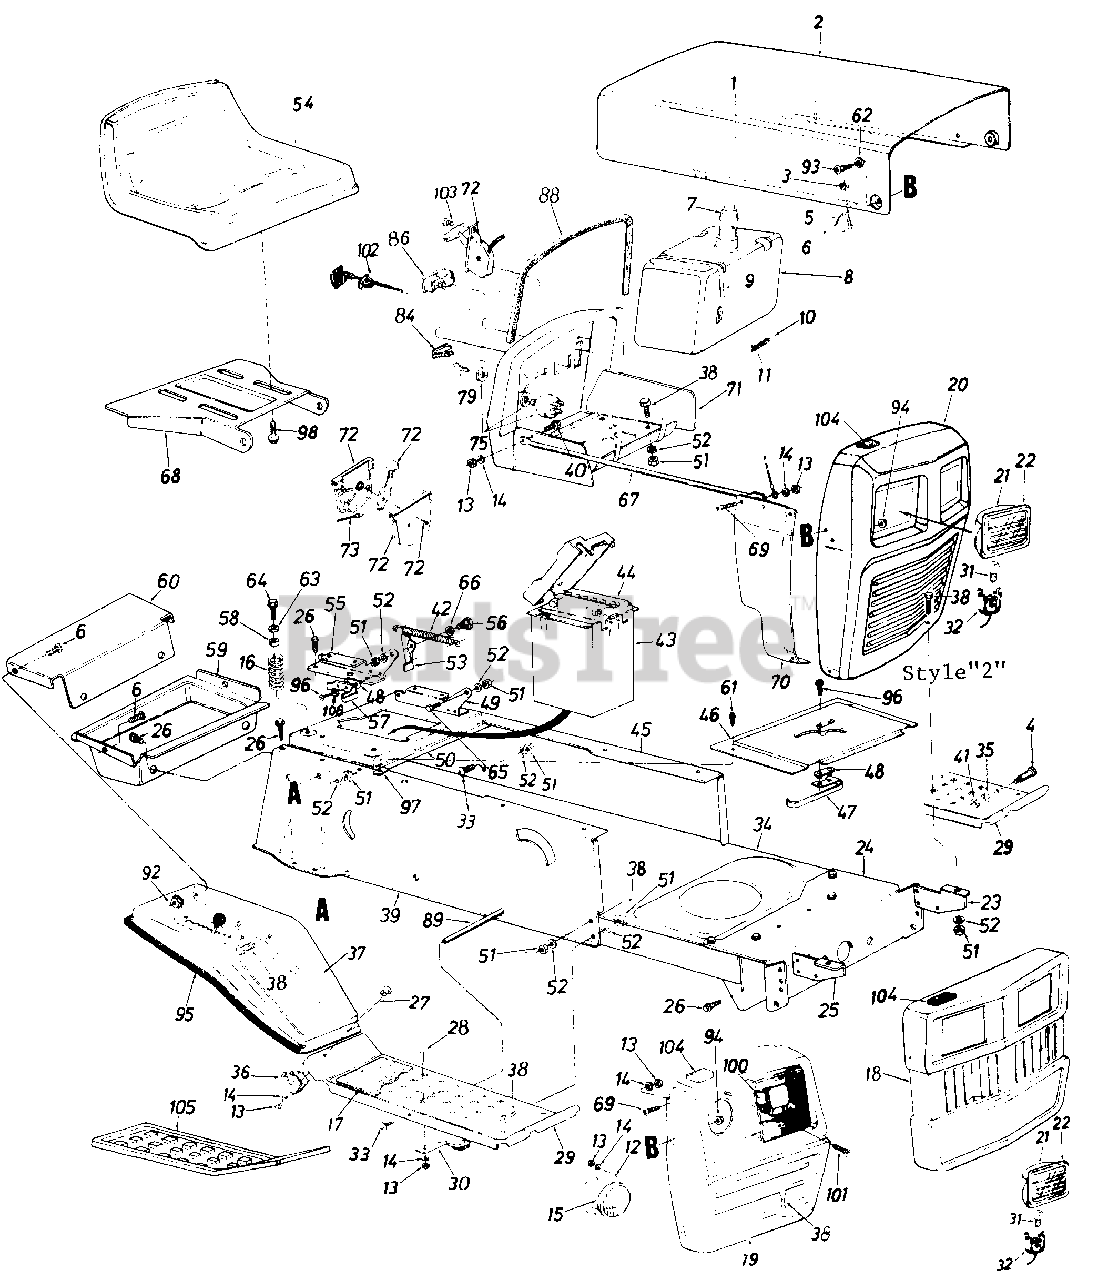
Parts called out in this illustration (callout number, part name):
1	Hood Spring
2	Hood
3	Hex Sems Nut #10-24 Thd.
4	Shld. Bolt .50" Dia. x .84"
5	Hood Stop 7" Lg.
6	Truss Hd. Scr. #10-24 x 1/2"
7	Fuel Cap Gauge
8	Fuel Tank
9	Tie Strap
10	Fuel Line
11	Hose Clamp
12	Headlight Retainer
13	Hex Nut 1/4-20 Thd.
14	L-Wash. 1/4" I.D.
15	Headlight*
16	Compression Spring
17	Foot Pad
18	Grille-Square Lights
22	Headlight Lens
23	Mounting Brkt.
24	Front Pivot Brkt.
25	Mounting Brkt.
26	Hex Wash. Hd. AB-Tap Scr. 5/16 x .75" Lg.
27	Carriage Bolt 1/4-20 x 2.0" Lg.*
28	Carriage Bolt 1/4-20 x .62"
29	Running Board
30	Blade Brake Ass'y.
31	Head Lamp
32	Twist Lock Lamp Socket
33	Truss Mach. Scr. 5/16-18 x .75" Lg.
34	Lower Frame
35	L-Wash. 3/8" I.D.
36	Fender Clamp
37	Fender
39	R.H. Side Frame
40	Hex Bolt 1/4-20 x .62" Lg.
41	Hex Nut 3/8-16 Thd.
42	Extension Spring 5.31" Lg.
43	Battery Box w/Cover
44	12-V Battery
45	L.H. Side Frame
46	Shift Cover
47	Reverse Safety Switch
48	Insulator Nut Plate
49	Seat Pivot Brkt. Support-L.H.
50	Hitch Plate
51	Hex Nut 5/16-18 Thd.
52	L-Wash. 5/16" I.D.
53	Seat Lift Brkt.
54	Seat 8-7/8" High
55	Seat Pivot Brkt. Support-R.H.
56	Shld. Bolt .437" Dia. x .268"
57	Spring Switch
58	Bushing
59	Tool Tray
62	Washer .39" I.D. x .62" O.D.
63	Fl-Wash. .344" I.D. x .875"
64	Hex Wash. Hd. Tap Scr. 5/16-18 x 1.0" Lg.
65	Shld. Bolt .437" Dia. x .162"
66	Spr-Wash. .445" I.D. x .75
67	Grille Support Rod
68	Seat Pivot Bracket
69	Truss Hd. Scr. 1/4-20 x .75"
70	R.H.-Grille Side Panel
72	Throttle Control Box Ass'y.
73	Throttle Control Wire-B&S
75	Ignition Switch
79	Ignition Key
84	Light Switch
86	Ammeter
88	Molding Strip 27" Lg.
89	Running Board Rod
92	Hex Sems Nut #10-24 Thd.
93	Shld. Bolt .375" Dia. x .125"
94	L-Nut 1/4-28 Thd.
95	Trim Strip-57" Lg.
96	Hex Wash. Hd. AB-Tap Scr. #8 x .50" Lg.
97	Speed Nut #10Z
98	Hex Tap Scr. 3/8-16 x .75"
100	Bezel
101	Oval C-Sunk Mach. Scr. 1/4 -20 x 1.5" Lg .
102	Choke Control 29" Lg.
103	Truss Mach. AB-Tap Scr. #10 x .50" Lg.
104	Foam Strip 3/8 x 1-1/8 x 11/2
105	Rubber Foot Pad-L.H.
106	Fiber Washer
